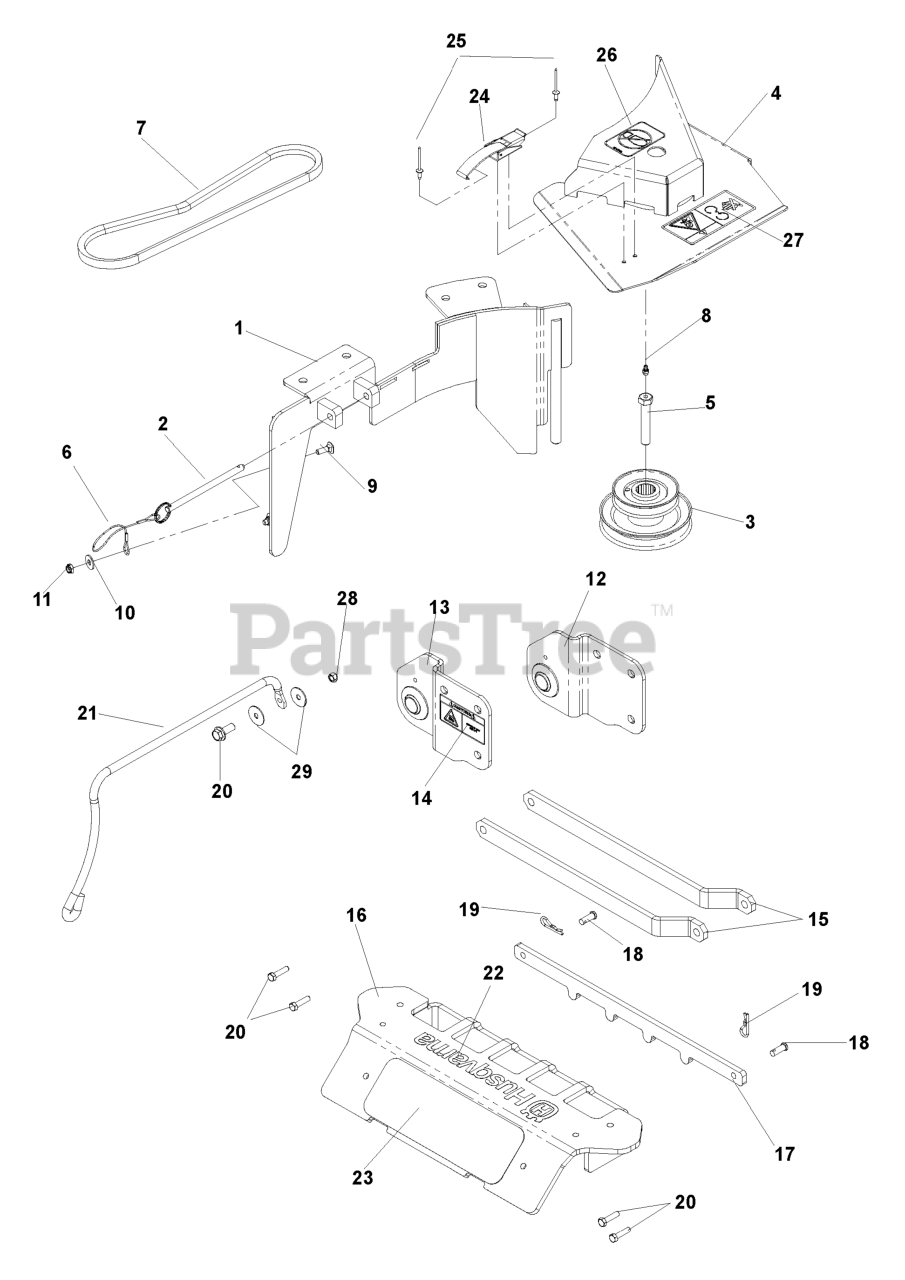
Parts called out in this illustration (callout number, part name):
1	BLOWER DECK PLATE
1	BLOWER DECK PLATE WLDMT, 52
1	BLOWER DECK PLATE WLDMNT, 61"
3	42/48 LG DBL HEX STACK PULLEY
3	52 LNG DOUBLE HEX STACK PULLEY
3	61 LNG DBL HEX STK PULLEY
4	BELT SHIELD ASSY 48"
4	BELT SHIELD ASSY 52"
4	BELT SHIELD ASSY 61"
5	HCS, 7/16-20 X 2 1/2, GR8
8	ZERK
9	RHSNB 1/4C X 3/4
10	WASHER 1/4 FLAT
11	JAM NUT 1/4C (2 2 PW01)
12	HITCH BRACKET WLD
13	HITCH BRACKET WLDMT, RT, MID
14	DECAL, HOT SURFACE
16	WEIGHT BAR, IZ
17	HOLD DOWN, WEIGHT BAR
18	CLEVIS PIN
19	RETAINER SPRING
20	HCS 5/16C X 1 1/4
21	HOSE SUPPORT
22	DECAL, HUSQ 12" BLUE
23	ANTI-SKID PAD
24	DRAW LATCH
25	RIVET, BLIND, 5/32 DIA
26	DECAL, NO STEP
27	DECAL, BELT DRIVE
28	NUT 5/16 NYLOC
29	WASHER 5/16 FLAT
